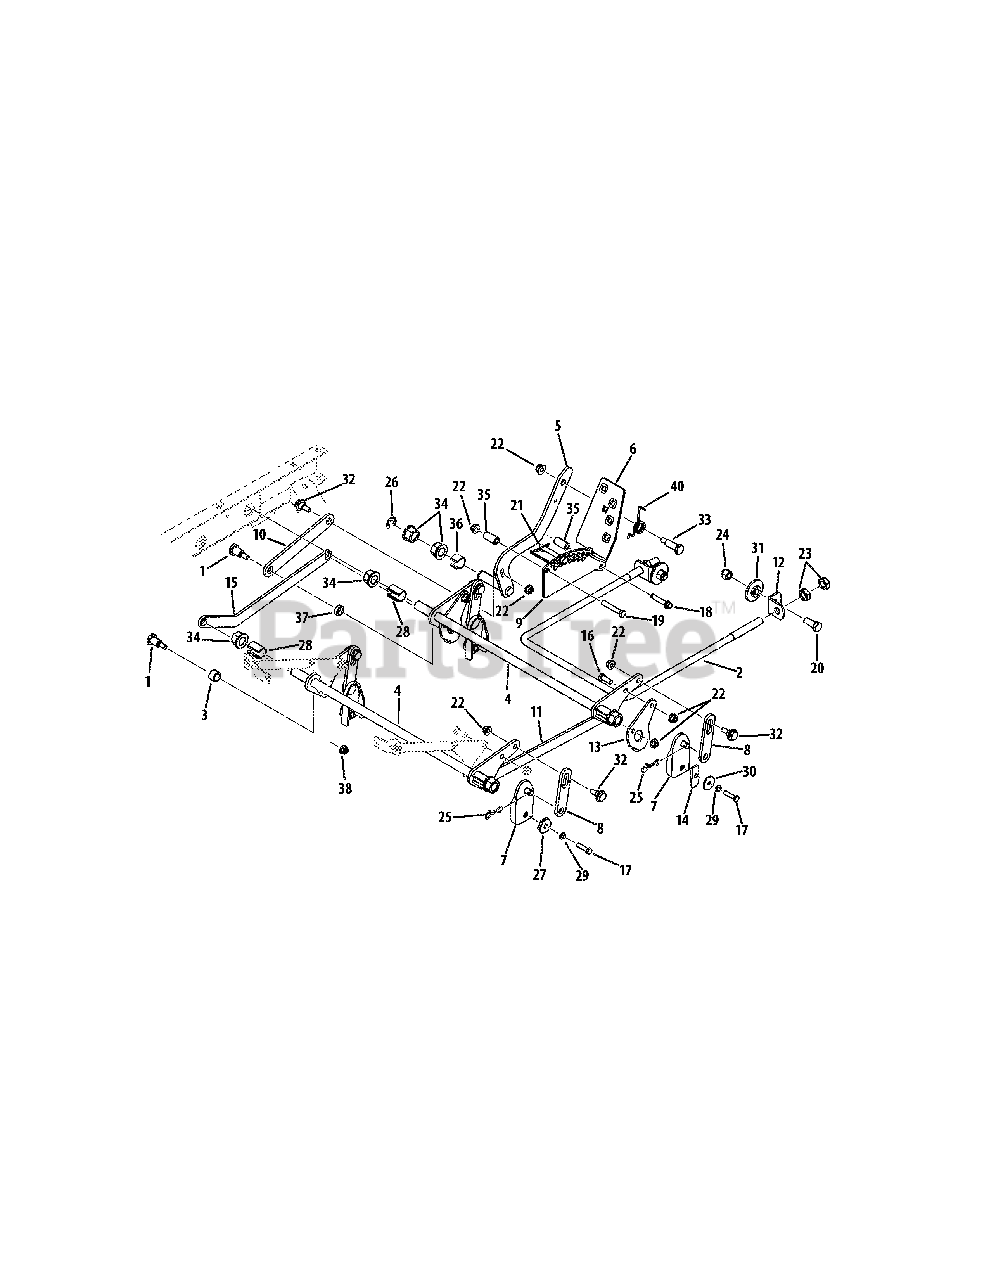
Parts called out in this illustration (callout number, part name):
1	Shoulder Screw, .625 x .830
3	Spacer, .632 x .877 x .548
4	Rock Shaft Assembly
5	Foot Lift Pivot Assembly
6	Lift Pedal Assembly
7	Deck Lift Adjustment Bracket
8	Lift Link Bracket
10	Pedal Link Plate
11	Mide Link Plate
12	Front Hanger Rod Bracket Mount
13	Deck Up Stop Bracket
14	Deck Lift Square Spacer
15	Mid-Angled Link Plate
16	Hex Screw, 3/8-16 x 1.00
17	Hex Screw, 5/16-18 x 1.25
18	Hex Washer Screw, 3/8-16 x 1.875
19	Hex Screw, 3/8-16 x 2.25
20	Hex Screw, 1/2-13 x 1.25
21	Lock Pin, .375 x 1.90
22	Flange Lock Nut, 3/8-16
23	Jam Nut, 1/2-13
24	Hex Lock Nut, 1/2-13
25	Click Pin, .092 x 1.64
26	E-Type Ring, .750
27	Adjustable Deck Gear
28	Spacer, .791 x .950 x 1.35
29	Lock Washer, 5/16
30	Flat Washer, .330 x 1.25 x .120
31	Shoulder Spacer, .9790 x .2025
32	Shoulder Spacer, 3/8-16 x .562 x .360
33	Shoulder Screw, .500 x 1.25 x 3/8-16
34	Hex Flange Bearing, .752
35	Spacer, .375 x .625 x 1.340
36	Spacer, .790 x .950 x .730
37	Spacer, .632 x .877 x .281
38	Flange Lock Nut, 7/16-20
39	Hex Lock Nut, 3/8-16
40	Torsion Spring, .75
